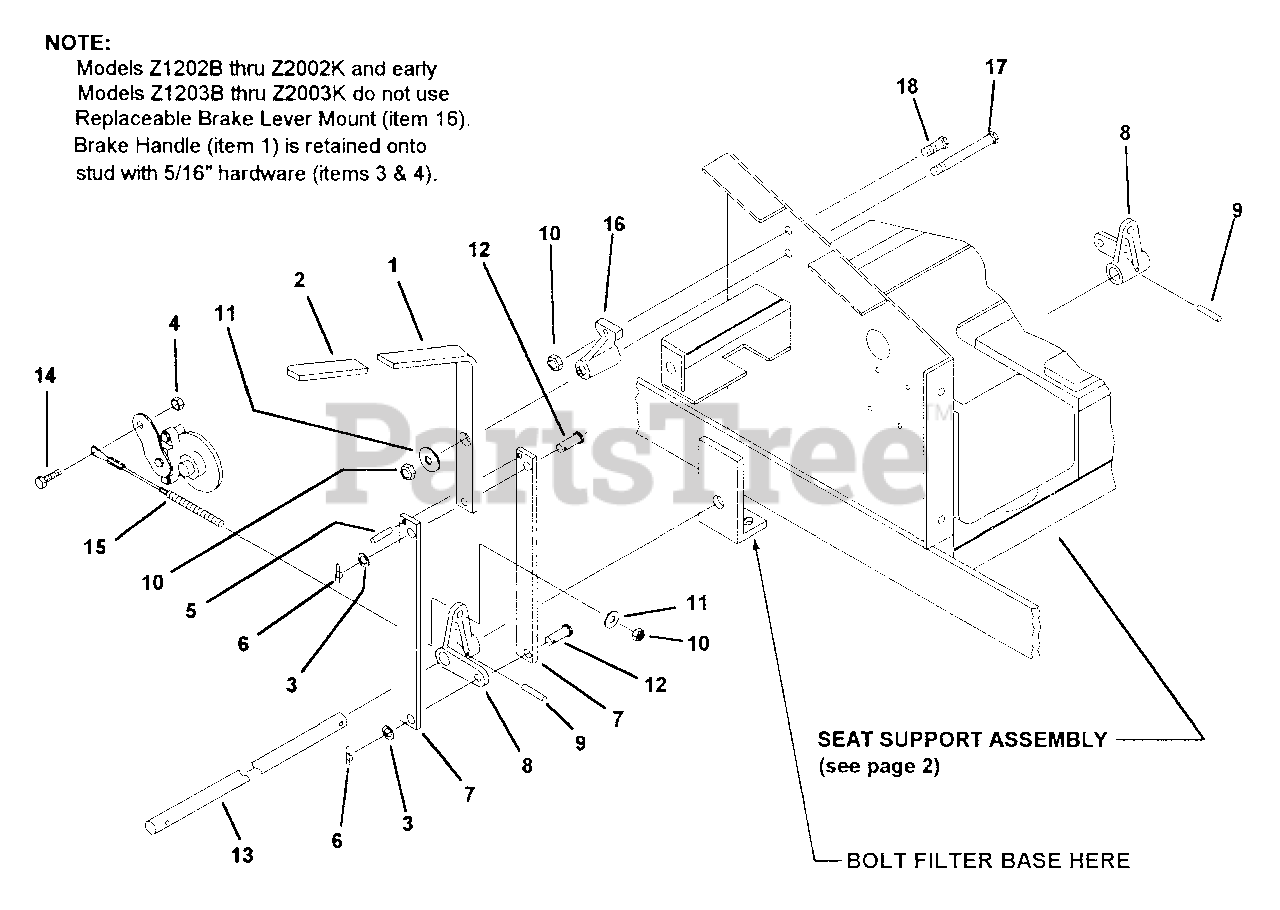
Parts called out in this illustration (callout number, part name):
1	BRAKE HANDLE
2	GRIP, HANDLE
3	WASHER, FLAT STD. 5/16"
4	NUT, 5/16-18 NYLOC
5	ROLL PIN, 3/16 X 7/8" LONG, SPIRAL
6	COTTER, RUE RING 5/16-3/8 PIN
7	HANDLE LINK
8	BRAKE ARM
9	ROLL PIN, 3/16 X 1" LONG SPIRAL
10	NUT, 1 /4-20 NYLOCK
11	WASHER, FLAT STD. 1/4"
12	CLEVIS PIN, 5/16 X 7/8" LONG
13	BRAKE ROD
14	BOLT, 5/16-18 X 3/4" GR. 5
15	CABLE ASSEMBLY, BRAKE
16	BRAKE LEVER MOUNT
17	BOLT, 1/4-20 X 3", Hex Head
18	BOLT, 1/4-20 x 1", Hex Head
